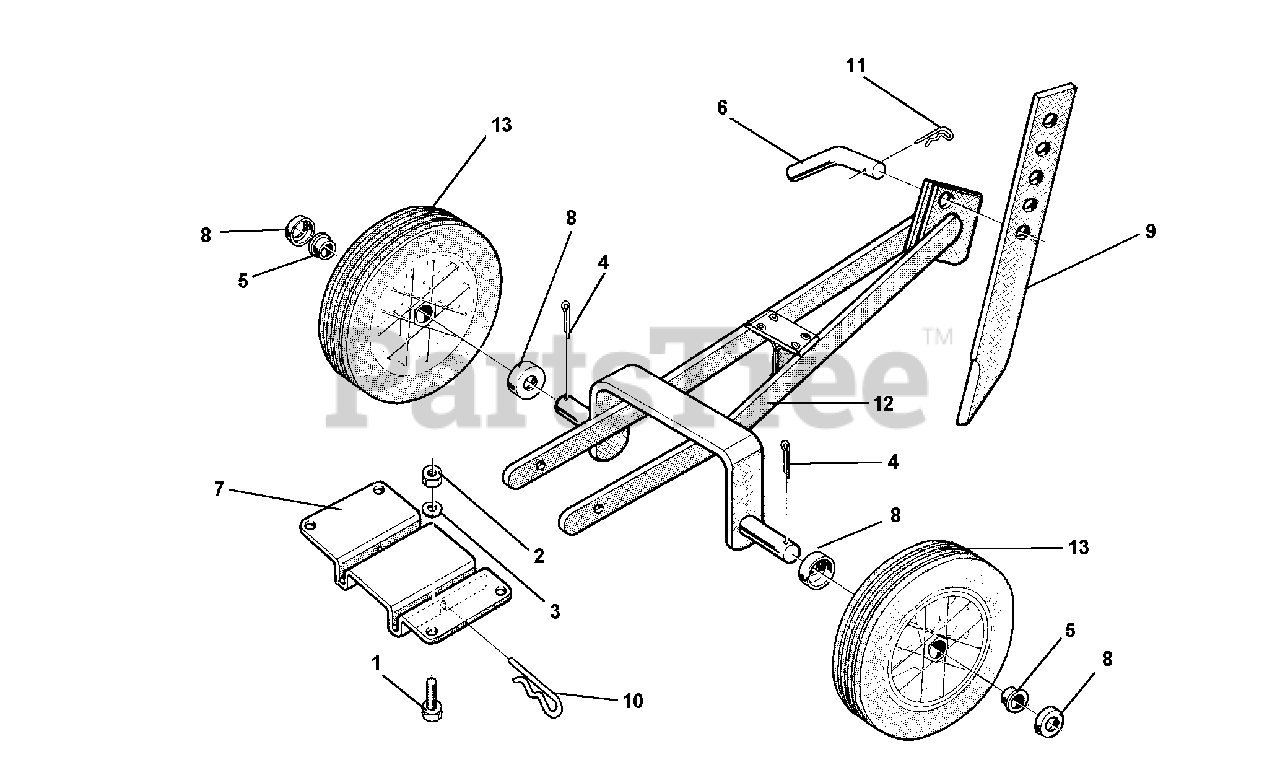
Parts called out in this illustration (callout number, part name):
1	SCREW M8 X 35
3	WASHER, LOCK 8.4
4	PIN, COTTER 4 X 25
6	ADJUSTMENT PIN
7	COUPLING PLATE
9	CENTRAL KNIFE
12	CENTRAL KNIFE SUPPORT
13	SMALL WHEEL
